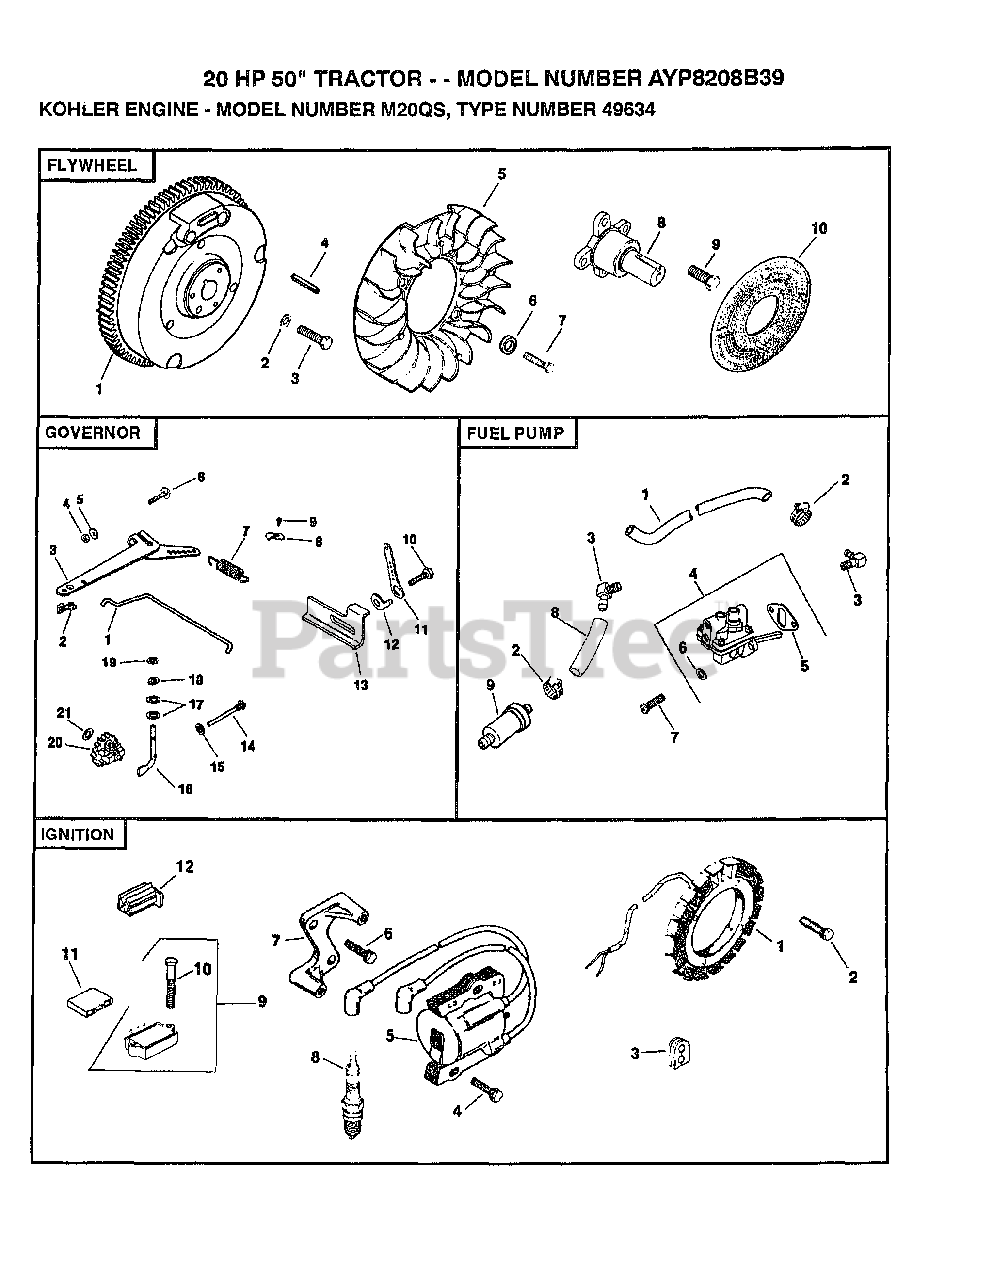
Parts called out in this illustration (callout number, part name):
1	KIT, GOVERNOR LINKAGE
3	SCREW, 3/8-24X1-1/4
3	ARM, GOVERNOR
4	SCREW, 1/4-20 X 1
5	GASKET, FUEL PUMP
6	WASHER, PLAIN 1/4
7	SCREW, HEX 1/4-20 X 5/8
7	SPRING, GOVERNOR
8	SHAFT, FRONT DRIVE
10	SCREEN, GRASS
11	LEVER, SPEED CONTROL
12	STOP, GOVERNOR
13	STOP, HIGH SPEED
19	WASHER, PLAIN 1/4
